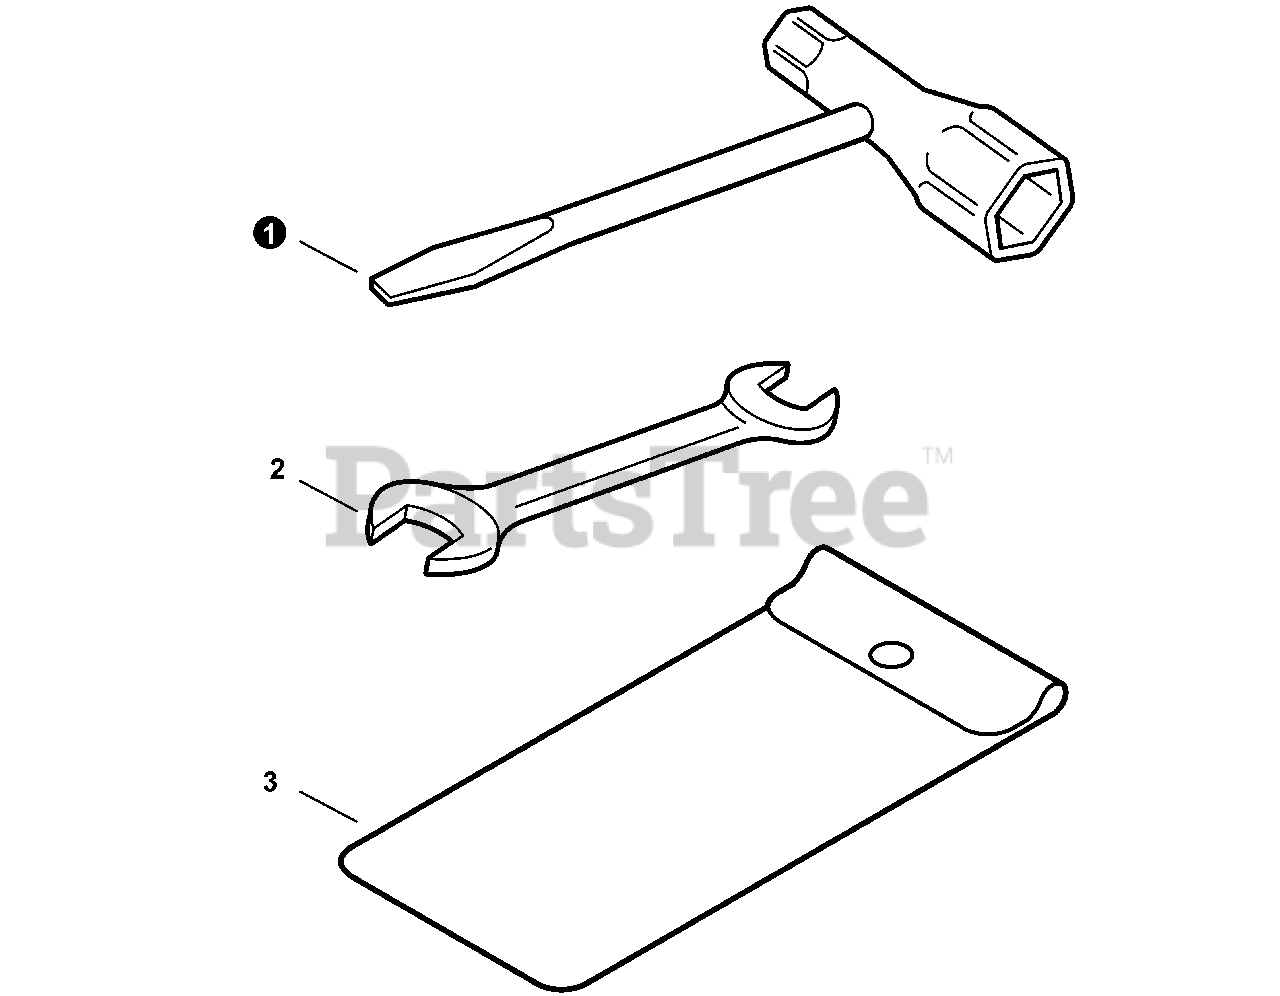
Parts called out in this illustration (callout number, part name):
1	T-WRENCH 17×19 L200
2	SPANNER 8×10
3	BAG, TOOL
